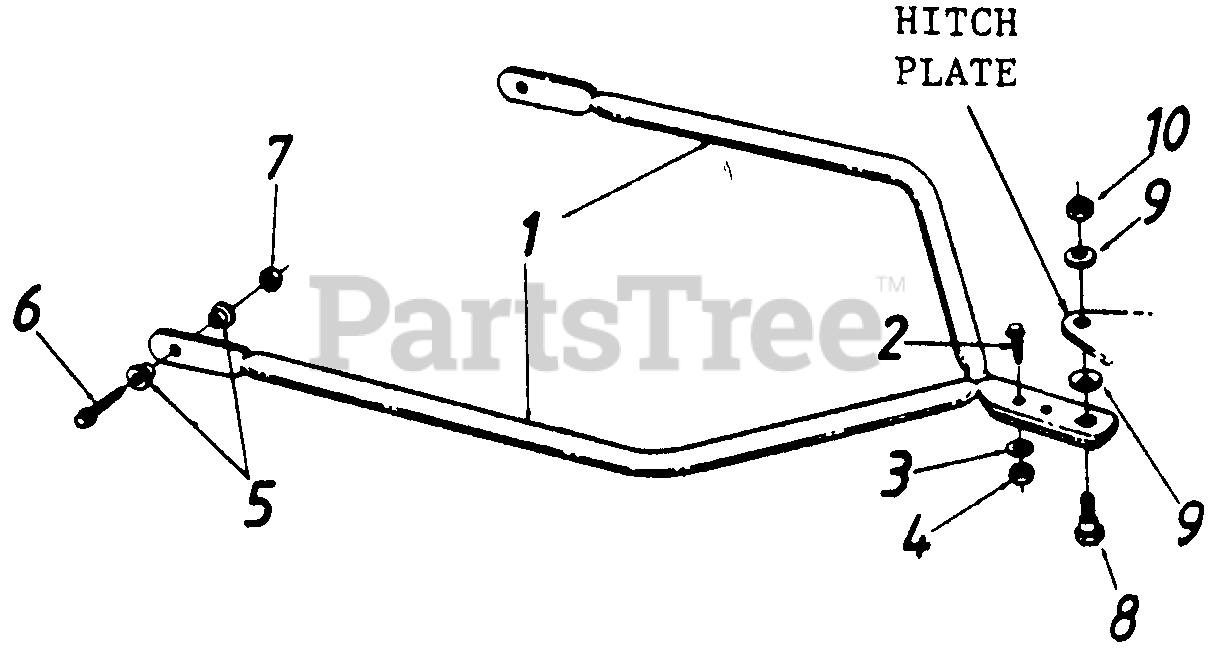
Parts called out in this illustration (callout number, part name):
3	L.-Wash. 1/4" I.D.
4	Hex Nut 1/4-20 Thd.
5	Shoulder Spacer
6	Hex Wash. Hd. Self-Tapp Scr. 5/16-18 x 1.0" 4.
7	Hex Nut 5/16-18 Thd.'
8	Shoulder Bolt
9	Bell-Wash. .39" I.D. x 1.12" O.D.
10	Hex Top Jam Nut 3/8-16 Thd.
